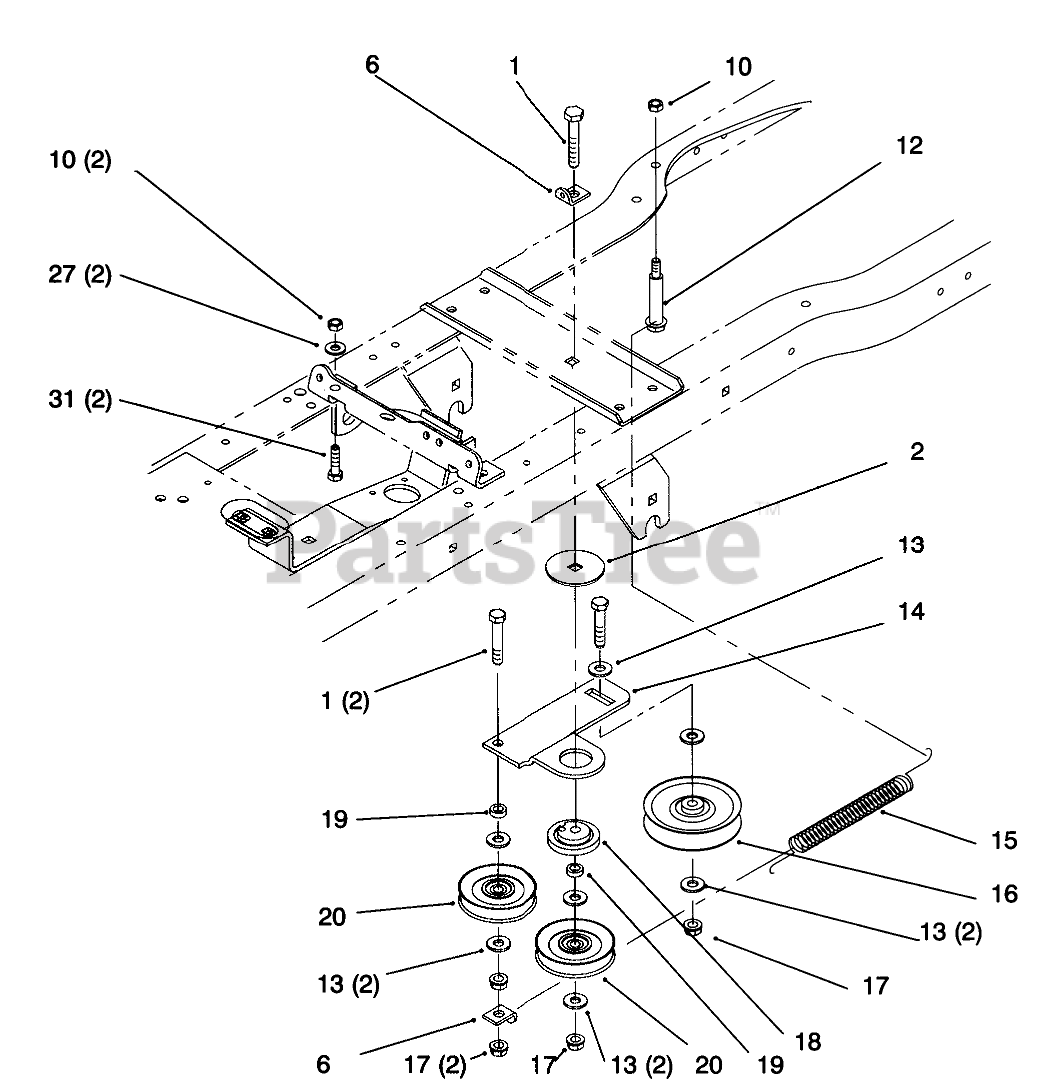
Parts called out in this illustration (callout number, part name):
1	Screw-HH (Only On: 72043, 72063, 72103)
2	Washer-Bearing (Only On: 72043, 72063, 72103)
6	Clip-Spring (Only On: 72043, 72063, 72103)
10	Nut-Lock (Only On: 72043, 72063, 72103)
12	Bolt-Shoulder (Only On: 72043, 72063, 72103)
13	Washer-Flat (Only On: 72043, 72063, 72103)
14	Arm-Idler (Only On: 72043, 72063, 72103)
15	Spring-Extension (Only On: 72043, 72063, 72103)
16	Pulley-Flat (Only On: 72043, 72063, 72103)
17	Nut-Lock (Only On: 72043, 72063, 72103)
18	Bushing (Only On: 72043, 72063, 72103)
19	Spacer (Only On: 72043, 72063, 72103)
20	Pulley-Idler (Only On: 72043, 72063, 72103)
27	Washer-Flat (Only On: 72043, 72063, 72103)
31	Screw-HH (Only On: 72043, 72063, 72103)
